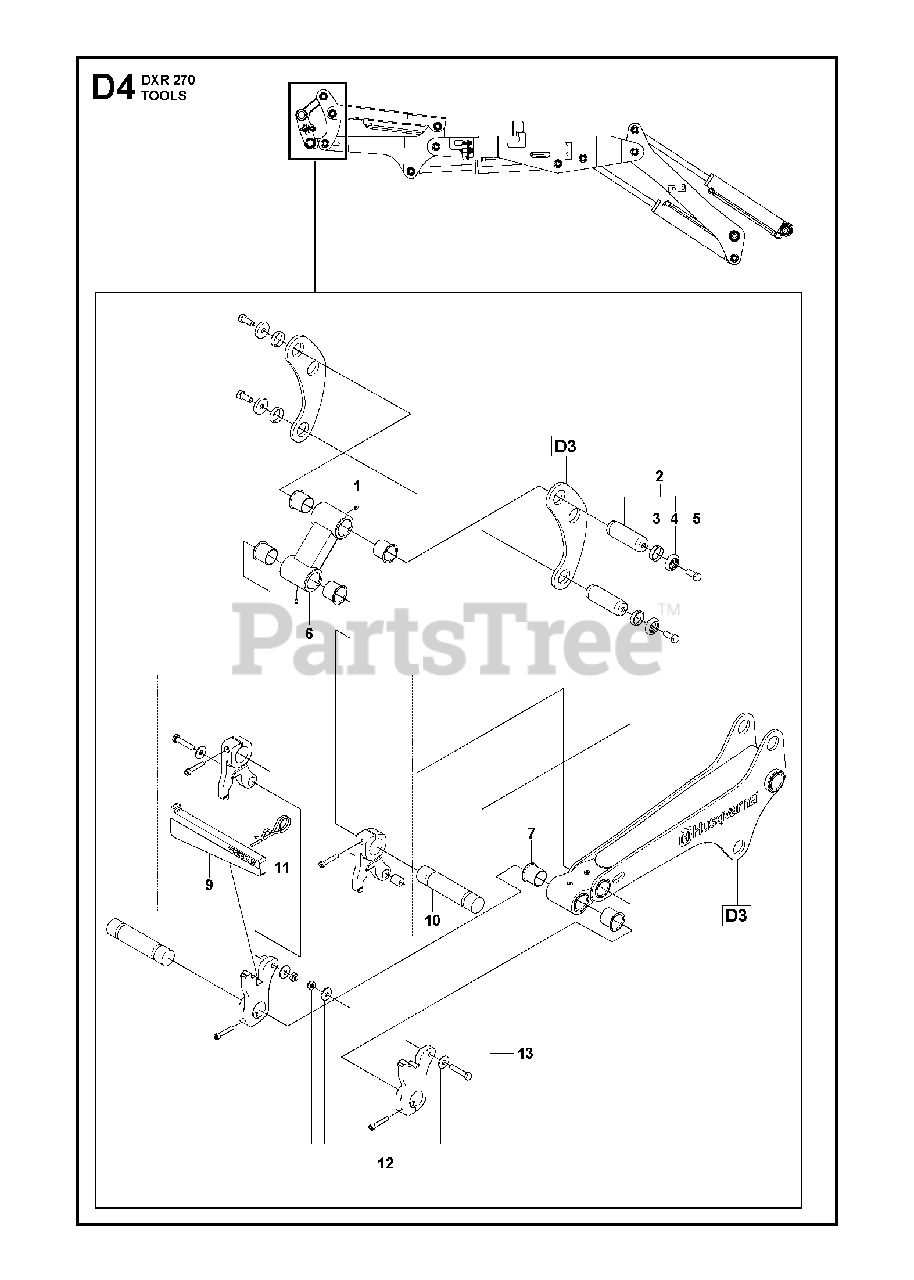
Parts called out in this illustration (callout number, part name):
9	WEDGEvalid for old tool hitch
10	SHAFTvalid for old tool hitch
11	CLIPvalid for old tool hitch
12	KITvalid for old tool hitch
13	HITCHvalid for old tool hitch
